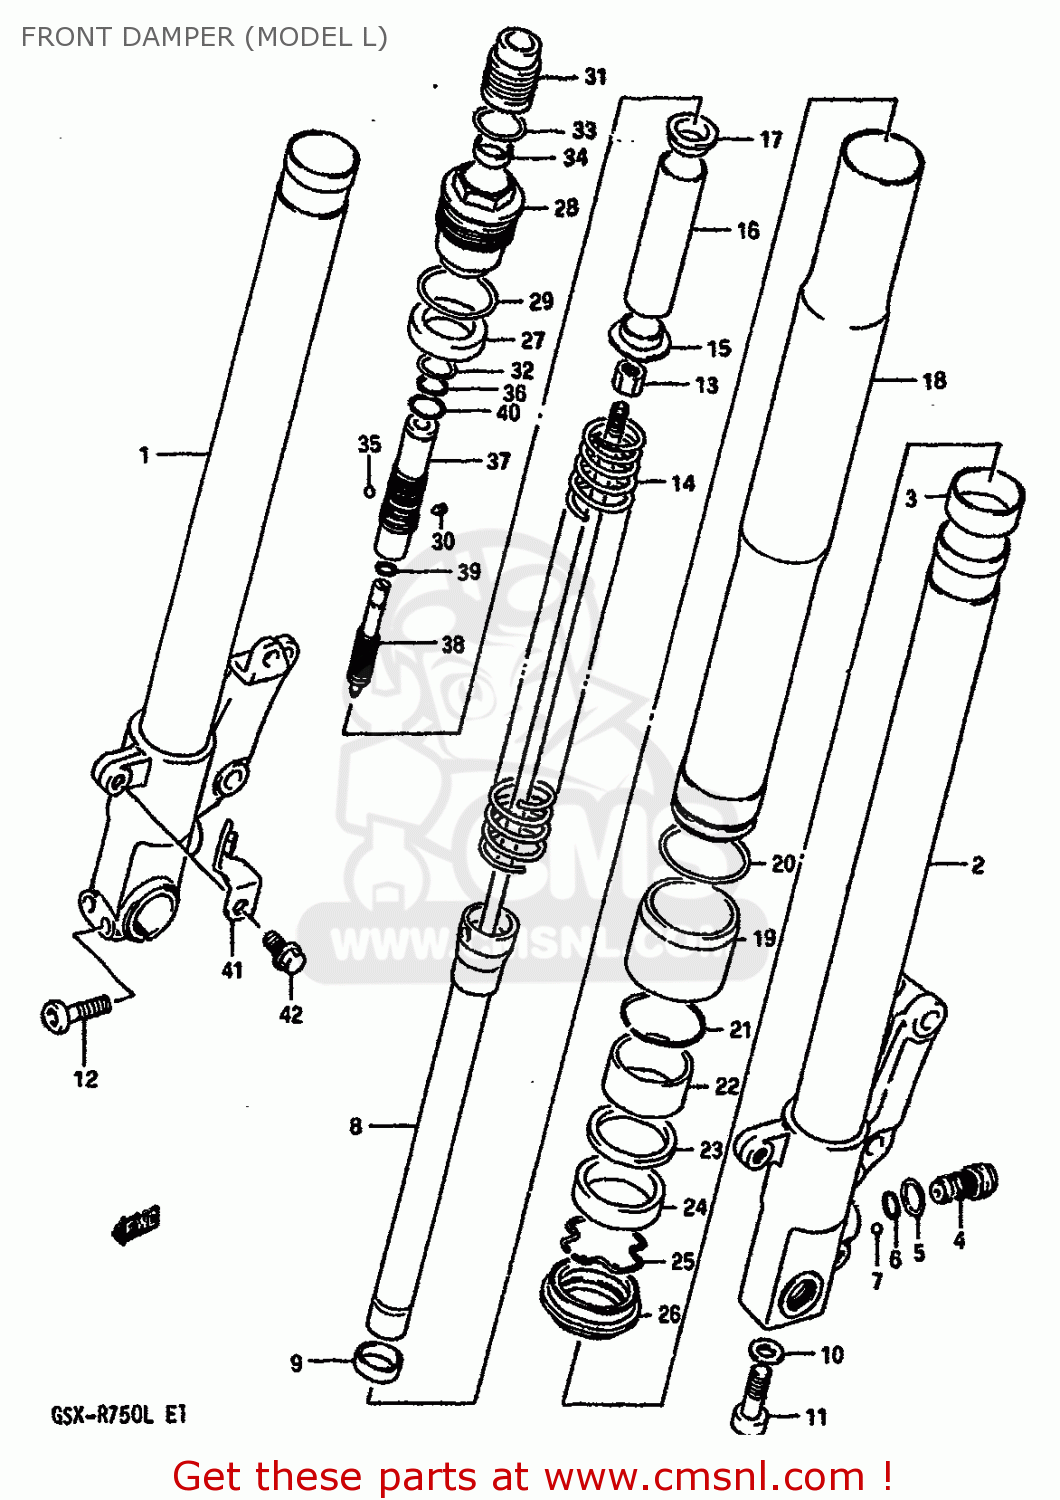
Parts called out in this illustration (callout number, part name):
1	TUBE,INNER,R
2	TUBE,INNER,L
3	BUSH,SLIDE
4	PIECE,ADJUSTER
5	O RING
6	BALL
7	EXPANDER
8	DAMPER,FRONT
9	PLATE,CENTERING
10	WASHER(10X15X1.5)
11	BOLT
12	BOLT
13	NUT
14	SPRING,MAIN
15	GUIDE,SPRING
16	SPACER,SPRING
17	JOINT,SPRING
18	TUBE,OUTER
19	CASE,OIL SEAL
20	O RING
21	RING,SNAP
22	BUSH,GUIDE
23	SPACER,SEAL
24	SEAL,OIL
25	CIRCLIP,FORK OIL SEAL
26	DUST SEAL,FRONT FORK
27	RUBBER,SEAT
28	BOLT, FORK
29	O RING,FORK BOLT
30	SCREW
31	ADJUSTER,SPRING
32	O RING
33	O RING
34	PLATE, SPRING ADJUSTER
35	BALL
36	EXPANDER
37	CASE,ADJUSTER
38	PIECE,ADJUSTER UPR
39	O RING
40	RING,STOPPER
41	PLATE,FRONT FENDER,LEFT
42	BOLT 8X12
